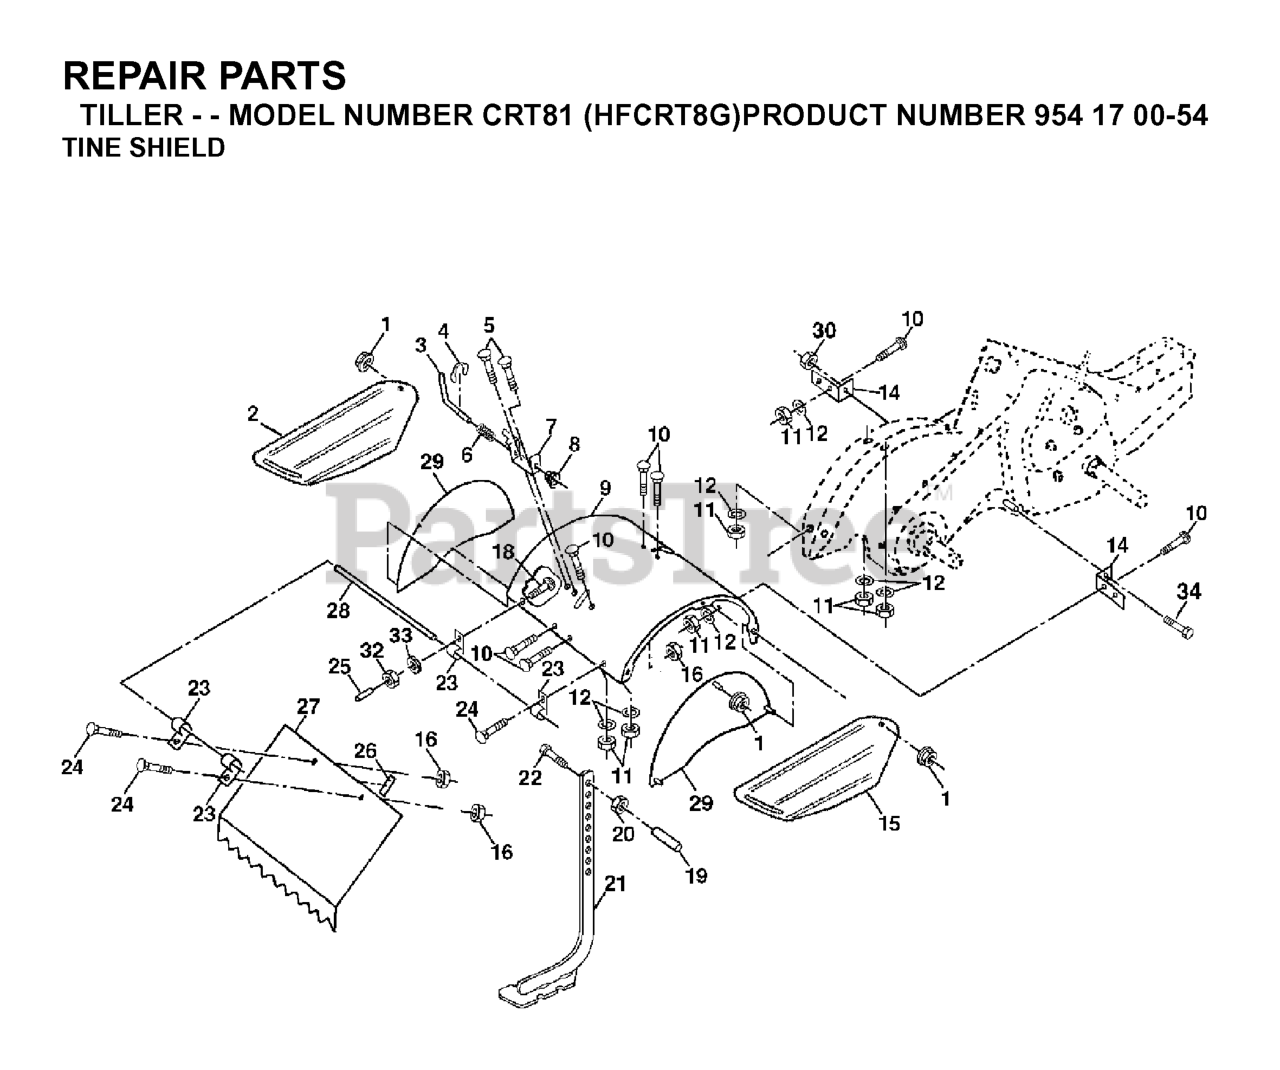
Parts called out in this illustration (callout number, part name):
1	NUT LOCK HEX FLANGE 5/16-18
2	TINE SHIELD
3	STAKE PIN TI
4	RING, KLIP
7	BRACKET.LATCH.STAKE.3.20.BLACK
8	SPRING CRT
9	SHIELD TINE
10	BOLT, RDHD SQNK 5/16-18 X 3/4
12	WASHER.LOCK.HVY.HLCL.SPR.5/16
14	BRACKET.TINE.SHIELD.TILLER
15	SHIELD
16	NUT T
20	NUT.HEX.3/8-16UNC
21	STAKE.ASM.DEPTH
22	BOLT.375-16
25	VINYL CAP TI
26	PAD IDLER TI
27	SHIELD.LEVELING.21".ORANGE
28	PIN, HINGE
29	SHIELD, SIDE
30	LOCKNUT-FLANGE 5/16-18
32	NUT
33	LOCKWASHER
34	Bolt Hex Flanged 5/16-18 Unc x 2
